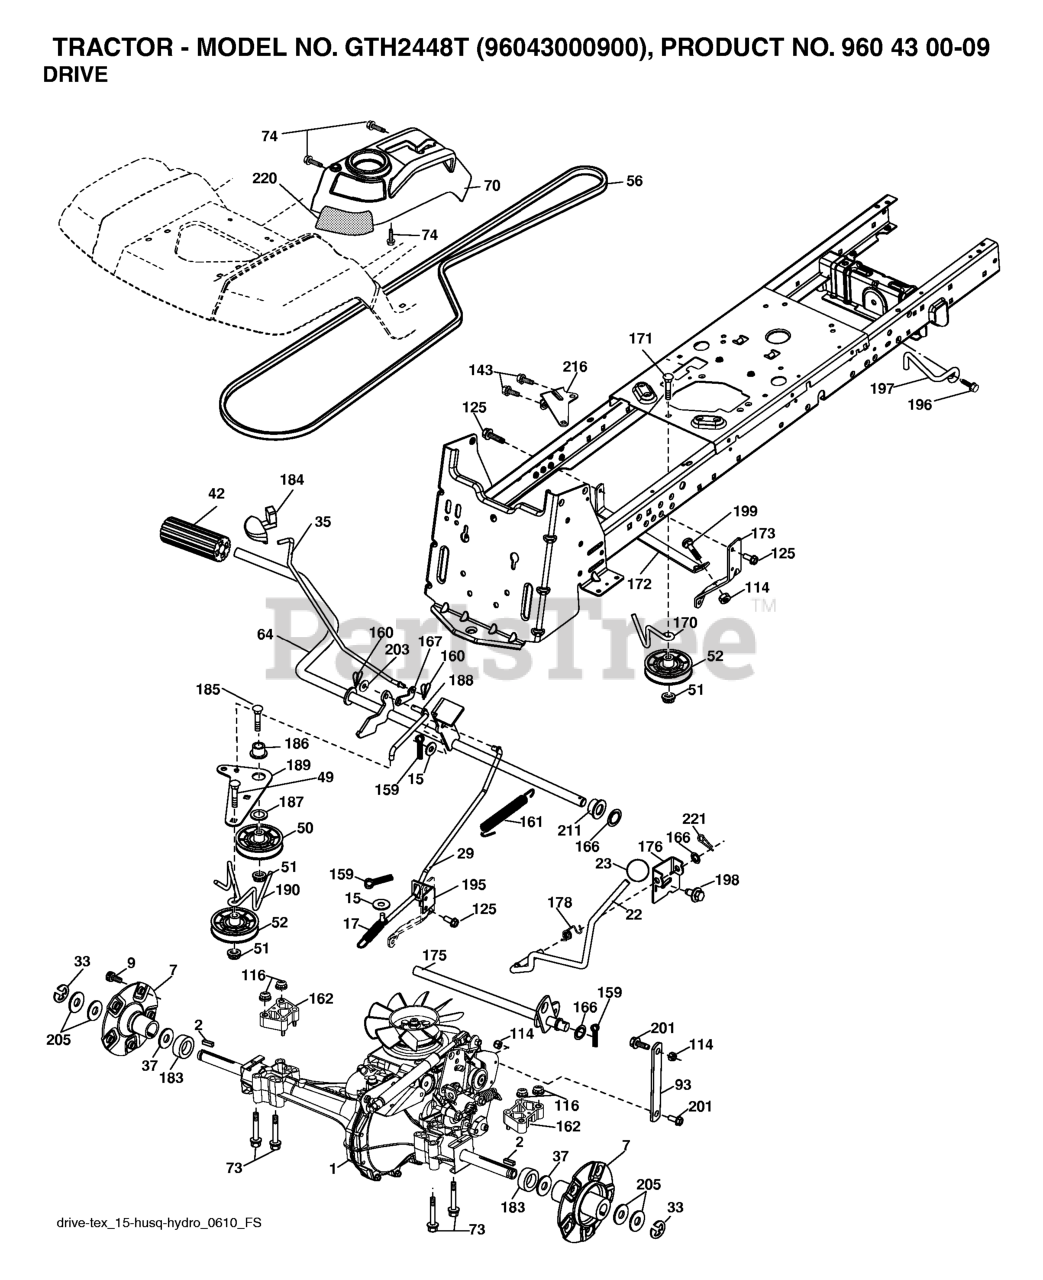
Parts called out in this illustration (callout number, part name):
2	KEY.SQUARE.187X2.500
7	HUB.ASM.WHEEL.REAR.22"
15	WASHER
17	SPRING.BRAKE.HG3000/3500
23	KNOB.DELUXE.(PISTOL.GRIP).BLAC
29	ROD.BRAKE.0610.PEDAL.CONTROL
35	ROD.BRAKE.PARKING.GT.H
42	PEDAL COVER T
50	IDLER.FLAT.910.OFFSET
51	NUT LOCK FLG 3/8-16 UNC
52	IDLER.V-GROOVE.910.OFFSET
64	SHAFT.ASM.PEDAL.BRAKE.
70	RP CONSOLE.ASM.HYDO.HUSQ.
73	BOLT.HEX.FLNG.5/16-18X3.75
74	SCREW.HI-LO.CONSOLE
93	LINK.SHIFT.T/A.0610.TE
114	NUT.71038.31-18.HEX.NYLOCK
116	NUT LOCK HEX FLANGE 5/16-18
125	SCREW
143	Screw 5/16-18 x 1/2 Hex, Self Tapping 5/16-18 x 1/2
159	COTTER PIN
160	RETAINER CLIP
161	SPRING.RETURN.CLUTCH.2006
162	SPACER.TRANSAXLE.18&22
166	NUT.PUSH.625.2006
167	LATCH.BRAKE.SPRING
170	KEEPER.V-IDLER.CENTER.
172	STRAP.TRQ.LH.FS.HG0510
173	STRAP.TORQUE.FS.0610.RH
175	SHAFT.ASM.SHFT.HG0510/
176	ARM.CLEVIS.ROD.SHIFT
178	SPRING.SHIFT.GT2006
183	SPACER.SPLIT.800X.350
184	HANDLE.PARKG.BRK.HUSQ X667
186	SPACER.RETAINER
187	WASHER 12/32X2X10GA
188	RP.LINK.CLUTCH.GROUND.DRIVE
189	BELLCRANK.GROUND.DRIVE.TEX.
190	KEEPER.BELLCRANK.DRIVE
195	BRKT.ROD.BRAKE.18/20/2
196	SCREW 3/8-16X1
197	BRKT.ANIT-ROTATION.CLUTCH
198	SCREW.7/16-14X7/8.FLAN
201	BOLT SHOULDER 5/16-18 UNC
203	WASHER
216	BRACKET.PULLEY.IDLER.W/TEX
220	REFLECTOR.RH.TEX GT
221	RETAINER.SPRING.CLIP.H
